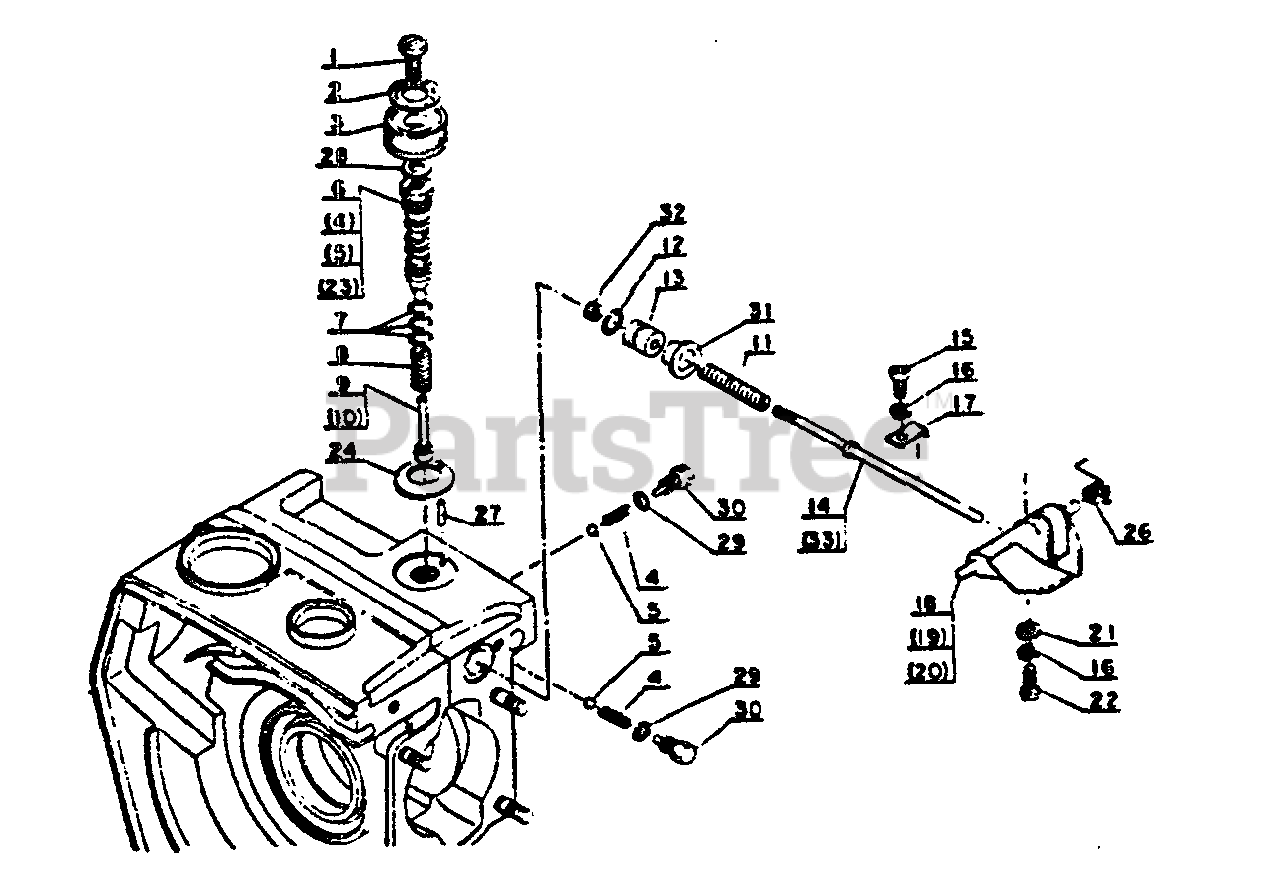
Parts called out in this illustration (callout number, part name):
1	SCREW
2	LABEL, CAUTION
3	DIAL, AUTO-OILER
4	SPRING, VALVE
5	VALVE, BALL
6	PUMP KIT
9	PUMP KIT
11	SPRING, OIL PUMP
12	O-RING
13	PUMP, OIL
14	ROD, OIL PUMP
15	SCREW 4×10
16	LOCKWASHER
17	SET PLATE, PUMP PISTON
18	PUSH LEVER, OIL PUMP
21	WASHER 4 MM
22	SCREW 4×14
24	FLAT SPRING
27	PIN, SPRING
28	SHIM
30	ADAPTER, OIL PUMP
31	SPRING SET
32	NUT 3 MM
